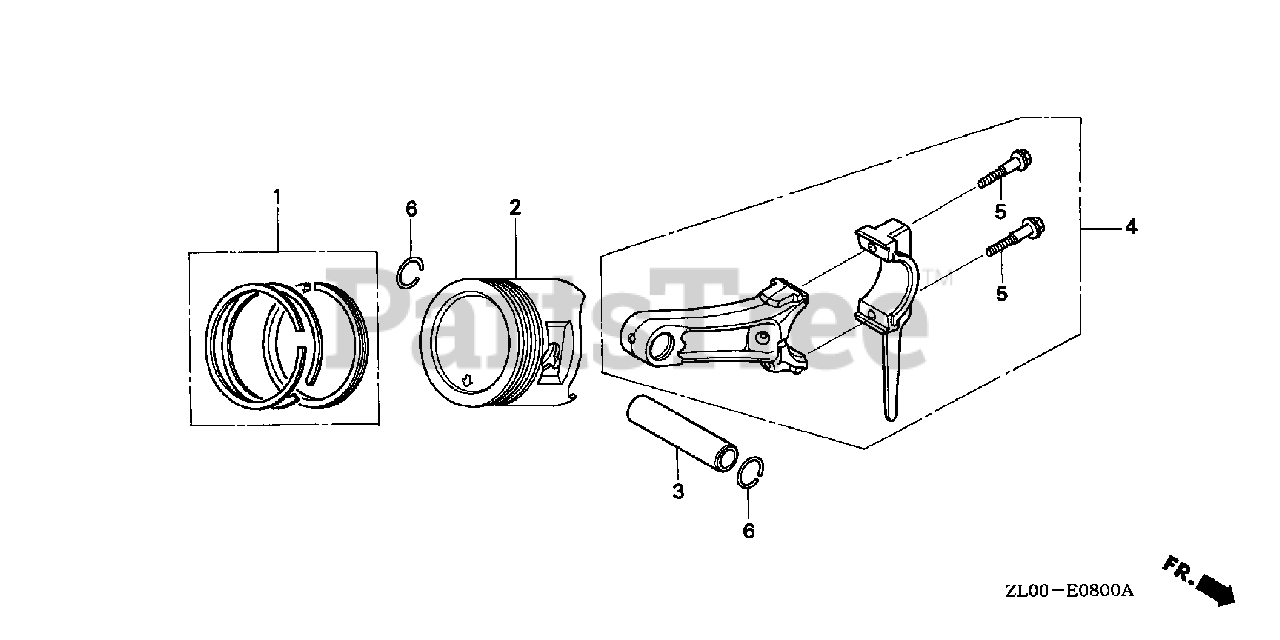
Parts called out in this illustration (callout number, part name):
1	RING SET, PISTON (STD)
1	RING SET, PISTON (OS 0.25)
1	RING SET, PISTON (OS 0.50)
1	RING SET, PISTON (0.75)
2	PISTON (STD)
2	PISTON (OS 0.25)
2	PISTON (OS 0.50)
2	PISTON (0.75)
3	PIN, PISTON
4	ROD ASSY., CONNECTING
5	BOLT, CONNECTING ROD
6	CLIP, PISTON PIN (18MM)
